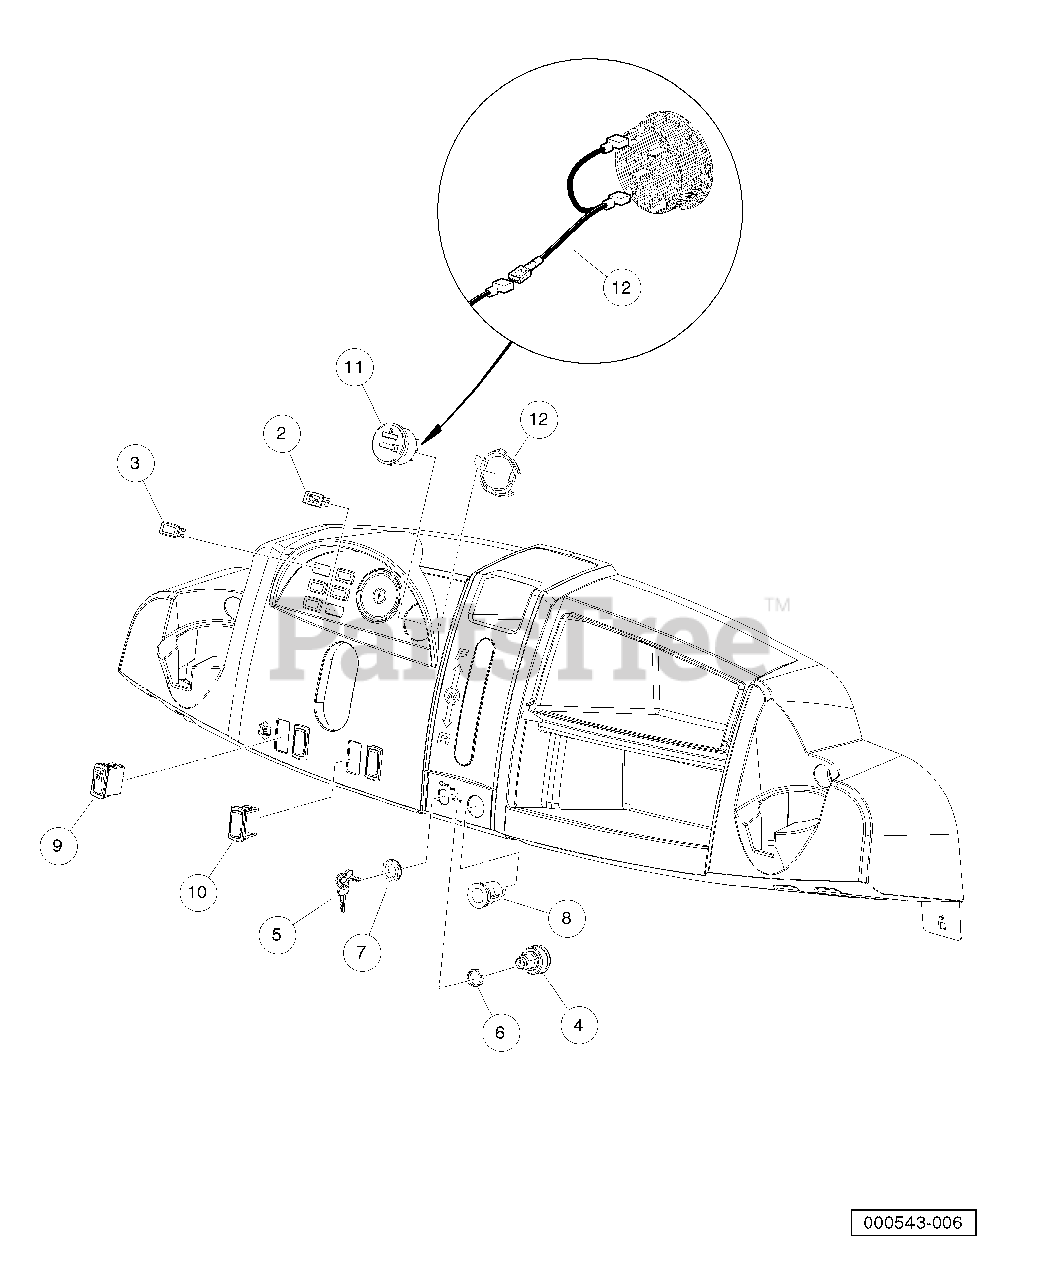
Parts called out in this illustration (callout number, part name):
2	Light, Oil
3	Plug, Hole
4	Key Switch 12v Key Start
6	Spacer, Keyswitch
7	Nut, Key Switch
8	Receptacle, Accessory
9	Switch, Rocker, Light
10	Cover, Hole, Switch, Rocker
11	Gauge Fuel-hour Sep Gnd
12	Clip, Meter, Round
13	Asm Wire Meter F-h Jumper
